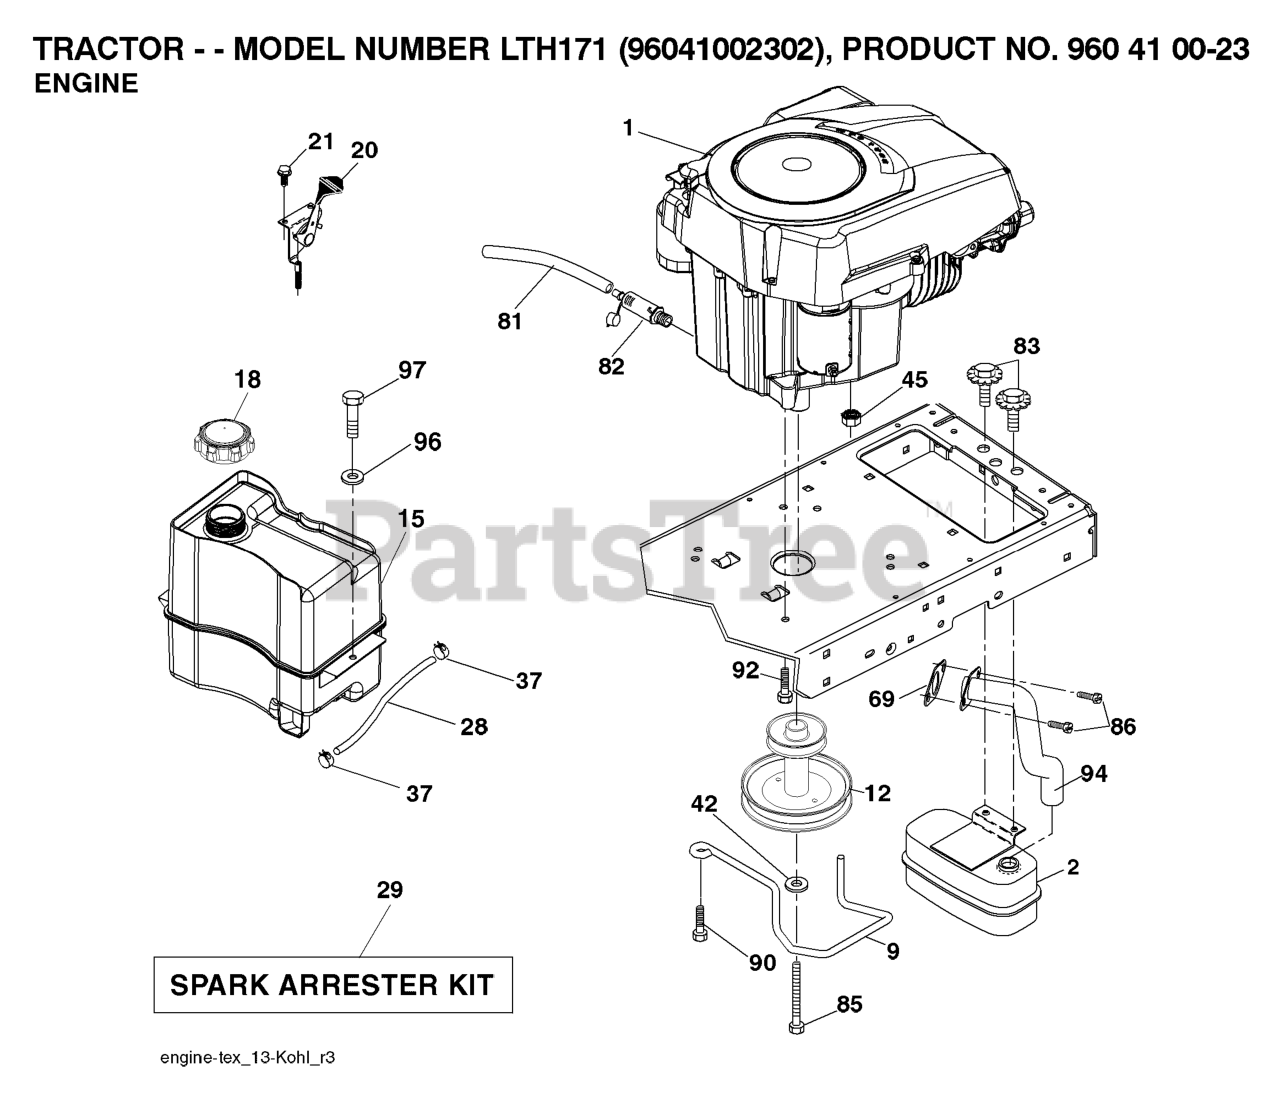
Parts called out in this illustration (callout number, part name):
2	MUFFLER.SINGLE.CYL.KOHL/B&S
9	KEEPER.BELT.ENGINE.4.2
12	PULLY ENGINE
15	RP TANK FUEL FRT 1.5 GAL
18	FUEL CAP
20	CONTROL.TH/CK.C.
21	SCREW
28	LINE.FUEL.20
29	KIT.SPARK ARRESTOR 794945 B&S
37	HOSE CLAMP
42	LOCKWASHER
45	NUT
69	GASKET.EXHAUST.KOHLER
81	TUBE, DRAIN OIL ASM.
82	PLUG DRAIN OIL EASY
83	BOLT.5/16-18UNCX3/4 W/SEMS.BLK
85	BOLT HEX 7/16-20X4-1/4"
86	SCREW.SOCKET HD.5/16-1
90	SCREW 3/8-16X1
92	SCREW 3/8-16X1
94	RP.TUBE.EXHAUST.KOHL.COURAGE
97	SCREW HEXWSHR 1/4-20X3/4
